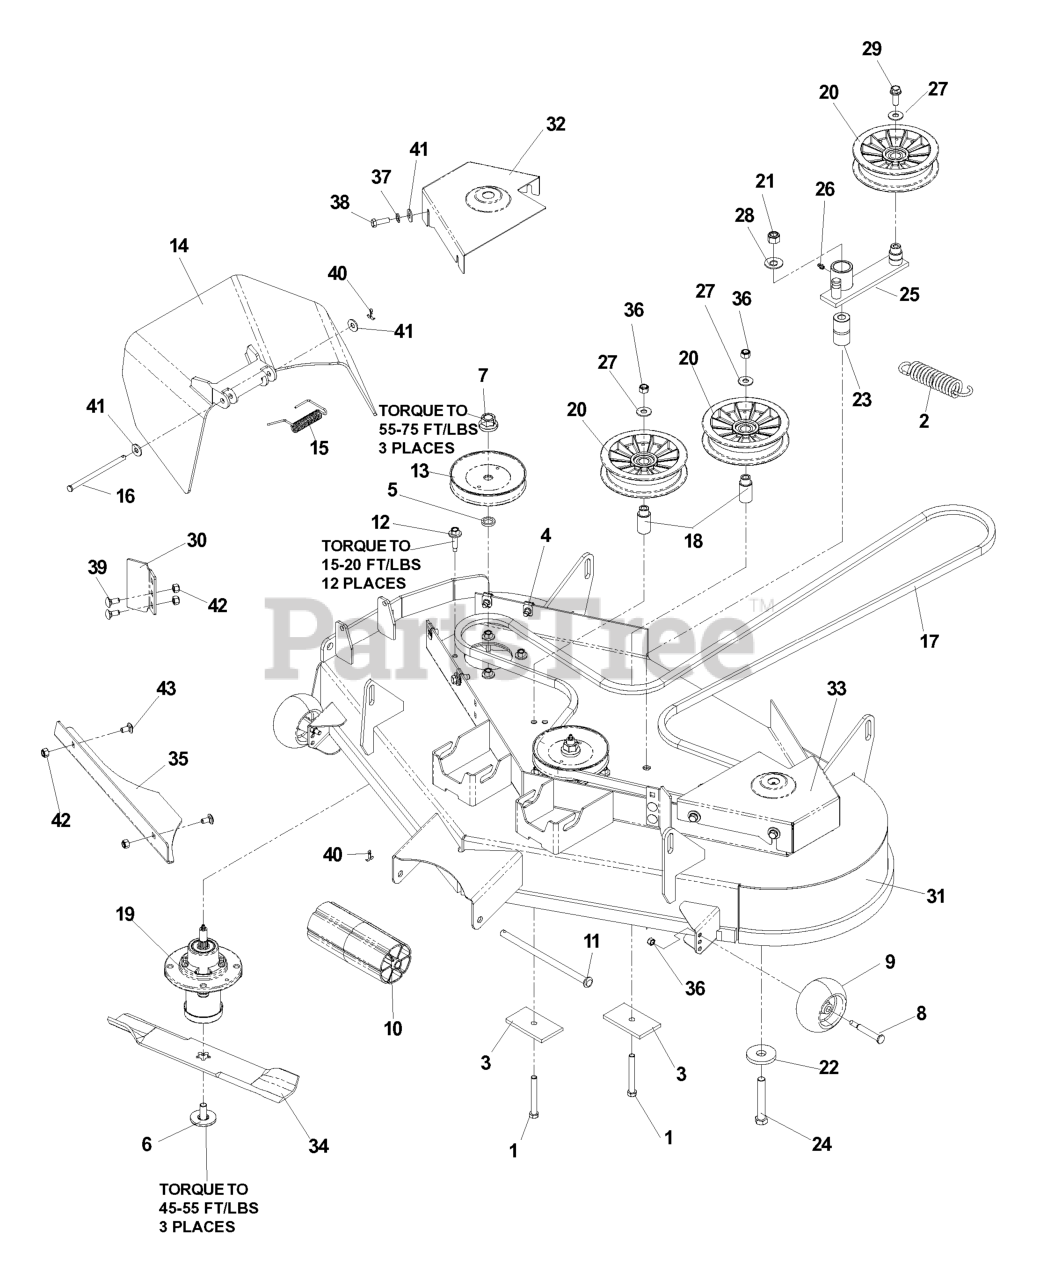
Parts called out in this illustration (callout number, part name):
1	HCS 3/8C X 3
3	SUPPORT PLATE
4	U-CLIP 5/16-18 NUT RETAINER
5	WASHER-SPACER
6	BOLT 7/16 ASM BLADE
7	LOCKNUT - 9/16
8	BOLT, SHOULDER
9	WHEEL GAGE DONUT
10	NOSE ROLLER 48"
11	NOSE ROLLER ROD
12	WASHER HEAD SCREW
13	PULLEY MANDREL
14	DISCHARGE CHUTE 48"
15	SPRING - TORSION
16	PIN-CLEVIS 5/16 DIA X 5.19 ZD
17	DECK BELT
18	IDLER BUSHING
19	MANDREL.DECK.ASSEMBLY
20	IDLER
21	NUT 1/2-13 HEX NYLOC ZD
22	WASHER, SUPPORT
23	PIVOT BUSHING
24	HCS 1/2C X 3 1/4
26	ZERK
27	WASHER 3/8 FLAT
28	WASHER 1/2 FLAT
29	4CS 3/8C X 1 SERRATED HEAD
31	DECK W/DECALS 48"
32	BELT SHIELD W/DECALS 48 RT
33	BELT SHIELD W/DECALS 48 LT
34	BLADE, 16-1/4"
35	CONFINEMENT PLATE 48" BLK
36	NUT 3/8-16 NYLOC
37	WASHER.LOCK.HVY.HLCL.SPR.5/16
38	HCS 5/16C X 1
39	BOLT 5/16C X 3/4" CARRIAGE
40	RP_COTTER PIN 1/8 X 3/4
41	WASHER 5/16 FLAT
42	NUT 5/16 NYLOC
43	CARRIAGE BOLT 5/16C X 5/8"
